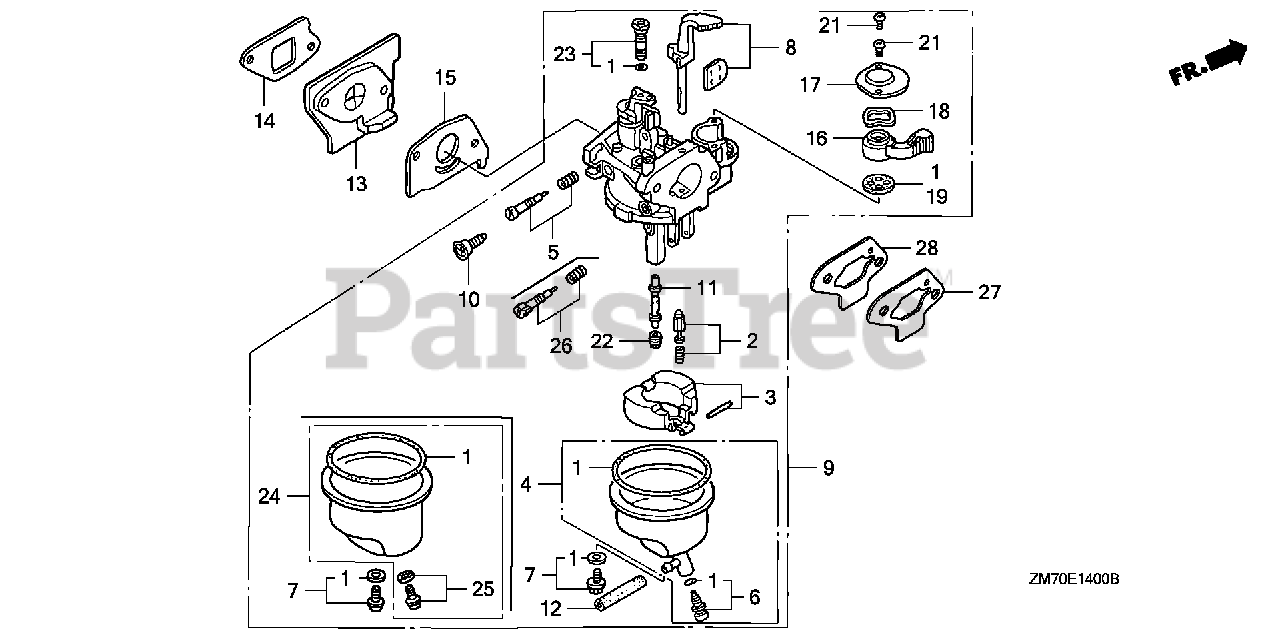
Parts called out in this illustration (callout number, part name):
1	GASKET SET
2	VALVE SET, FLOAT (SEAT NOT INCLUDED)
8	CHOKE SET (CARBURETOR NO.)
9	CARBURETOR ASSY. (BF32E C)
9	CARBURETOR ASSY. (BF32E D)
9	CARBURETOR ASSY. (BF32E G)
10	SCREW, THROTTLE STOP
11	NOZZLE, MAIN (CARBURETOR NO.)
13	INSULATOR, CARBURETOR
14	GASKET, INSULATOR
15	GASKET, CARBURETOR
16	LEVER, PETCOCK
17	PLATE, LEVER SETTING
18	SPRING, PETCOCK LEVER
19	GASKET, PETCOCK
21	SCREW, PAN (3X6)
22	JET, MAIN (#48) (CARBURETOR NO.)
22	JET, MAIN (#50)
22	JET, MAIN (#52) (CARBURETOR NO.)
22	JET, MAIN (#55) (CARBURETOR NO.)
23	JET SET, PILOT (#35)
24	CHAMBER SET, FLOAT
25	SCREW SET, DRAIN
26	SCREW SET, PILOT (CARBURETOR NO.)
26	SCREW SET (CARBURETOR NO.)
